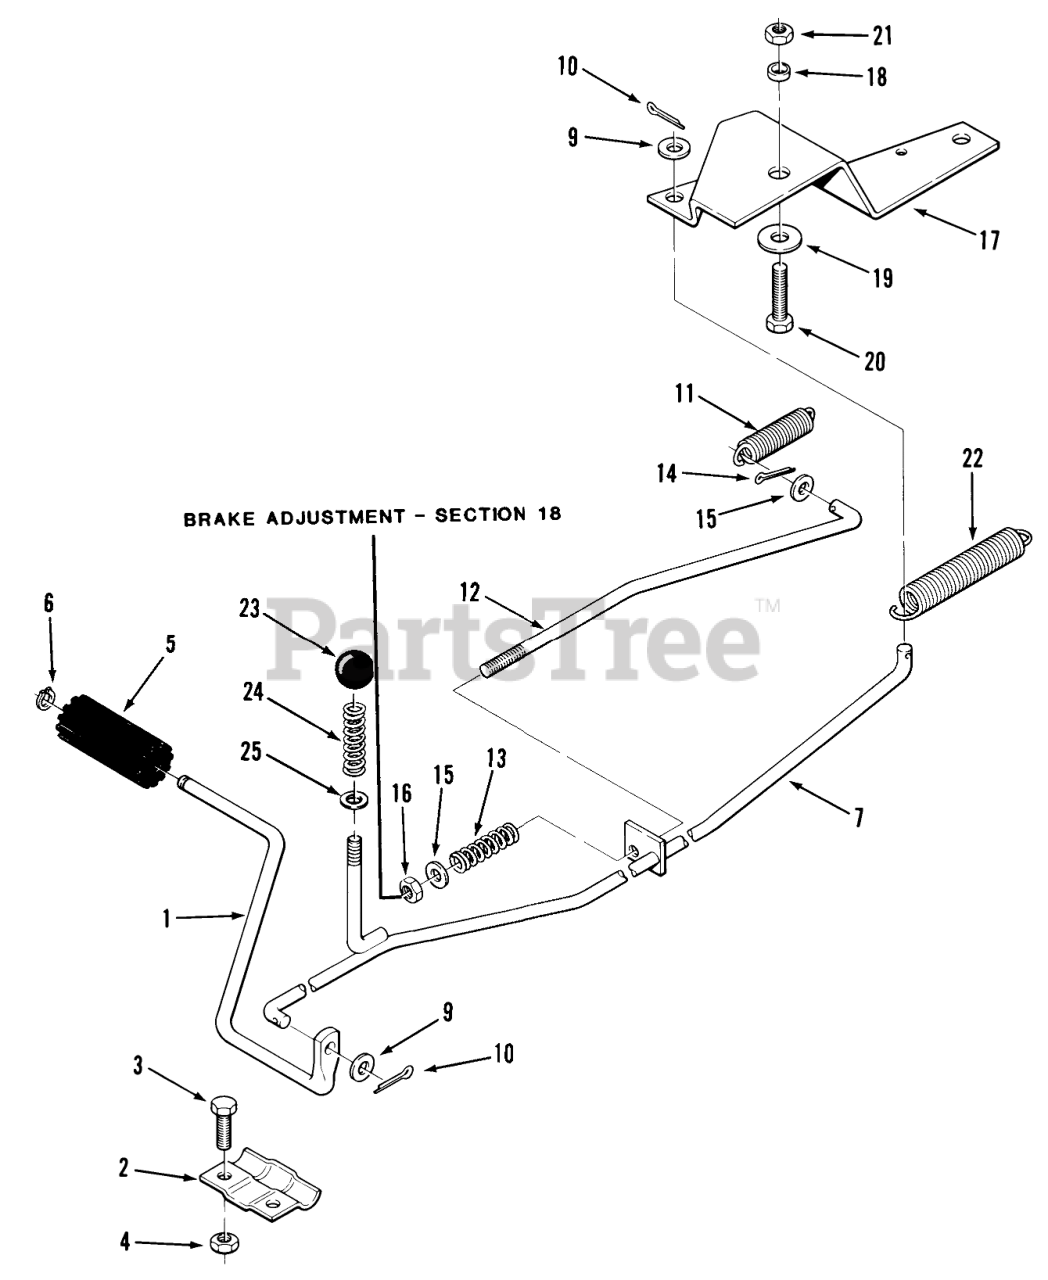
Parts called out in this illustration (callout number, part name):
1	ROD-BRAKE PEDAL R
2	SPINDAL SUPPORT R
3	Bolt
4	NUT
5	PAD-CLUTCH/BRKE PDL
6	Grip Ring
7	Clutch Rod Assy
9	Washer
10	Cotter Pin
11	SPRING-EXTENSION
12	ROD BRAKE
13	Brake Spring
14	Cotter Pin
15	Washer
16	NUT
17	LEVER CLUTCH R
18	SPACER
19	WASHER
20	Bolt
21	NUT
22	SPRING EXTENSION
23	KNOB
24	SPRING
25	WASHER NYLON
